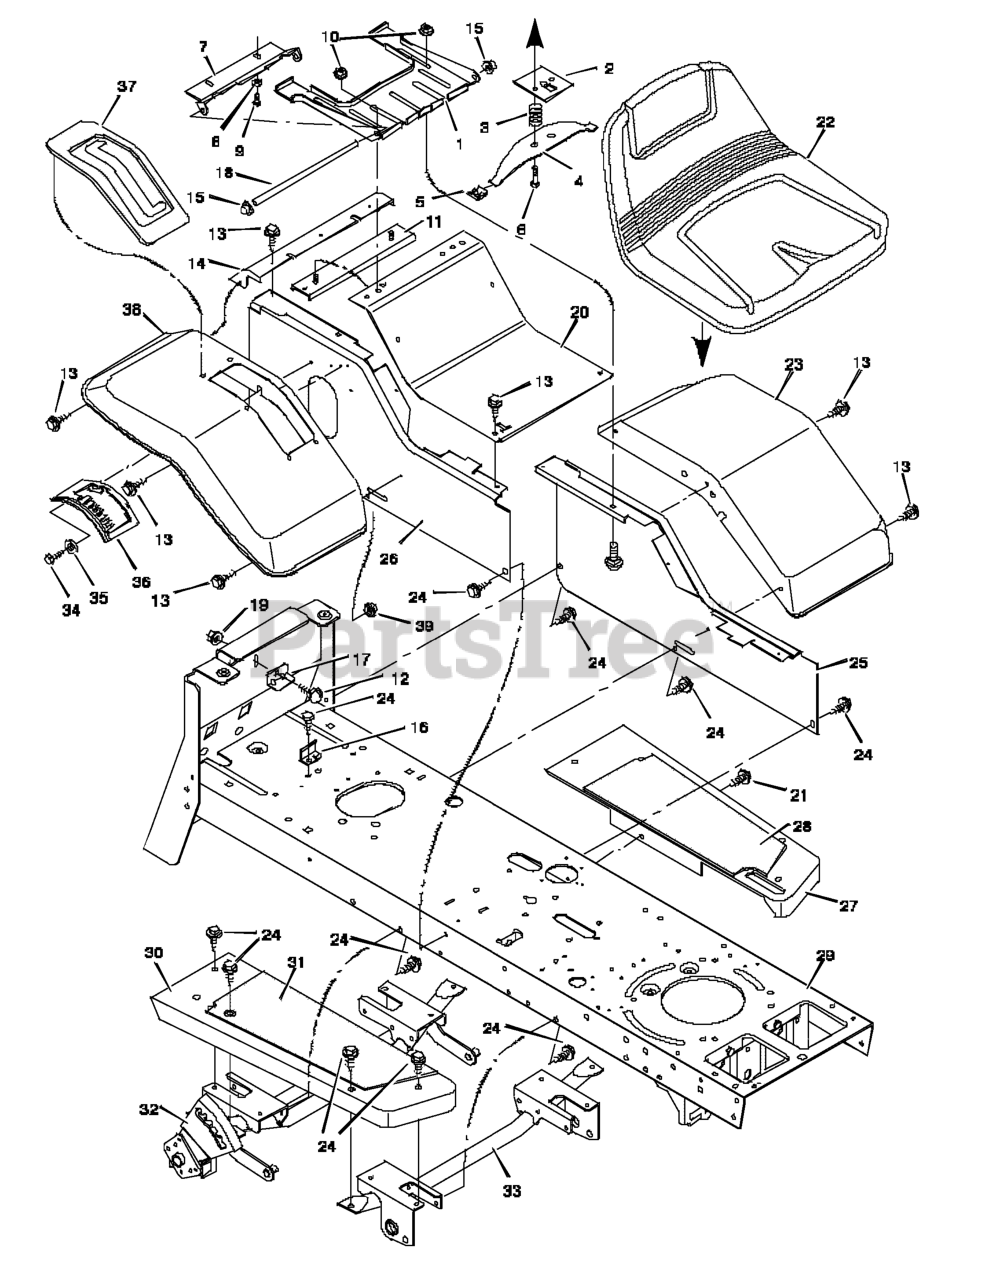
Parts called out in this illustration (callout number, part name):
1	Bracket, Seat
2	Plate Assembly, Switch
3	Spring, Compression
4	Spring, Seat
5	Glide, Spring
6	Bolt, Shoulder
7	Support, Seat
8	Lockwasher
9	Bolt, Hex
10	Locknut, Flange
11	Channel Assembly
12	Bolt, Carriage
14	Insert, Rear
15	Push On Cap
16	Clip, Battery
17	Clamp, Battery
18	Rod, Pivot
19	Locknut
20	Panel, Top
21	Fastener, Panel
25	Panel, Left
26	Panel, Right
27	Running Board, Left
28	Mat, Left
29	Frame Channel
30	Running Board, Right
31	Mat, Right
32	Lifter and Support Assembly
33	Support Assembly, Front
36	Gate, Shift
37	Cover, Shift
38	Fender, Right
39	Locknut
